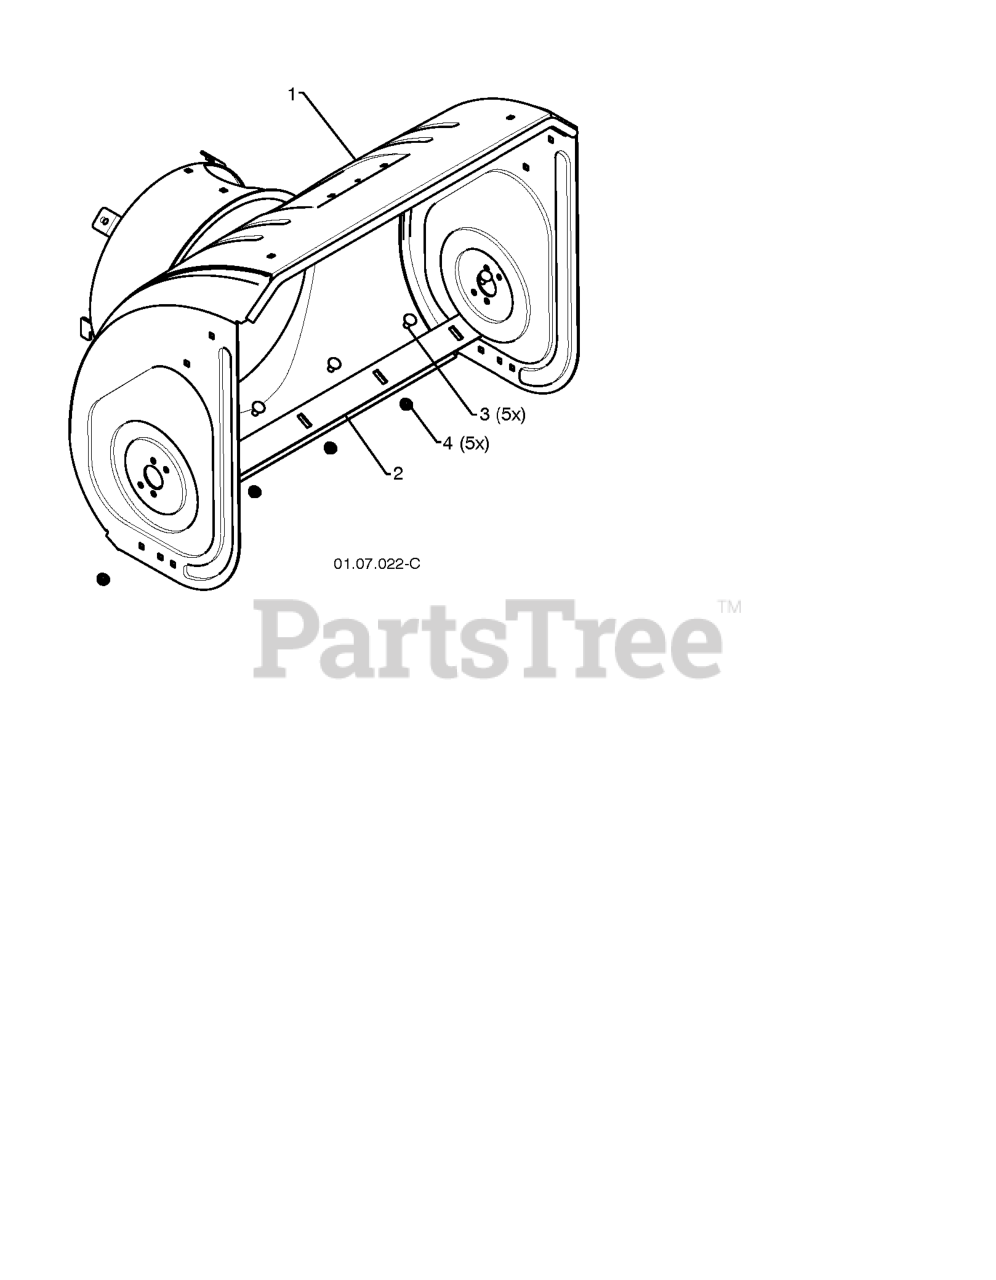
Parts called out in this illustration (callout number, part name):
1	HOUSING.AUG.WELDMENT.27.ORANGE
2	BAR, SCRAPER
3	BOLT
4	NUT.FLANGE.5/16
